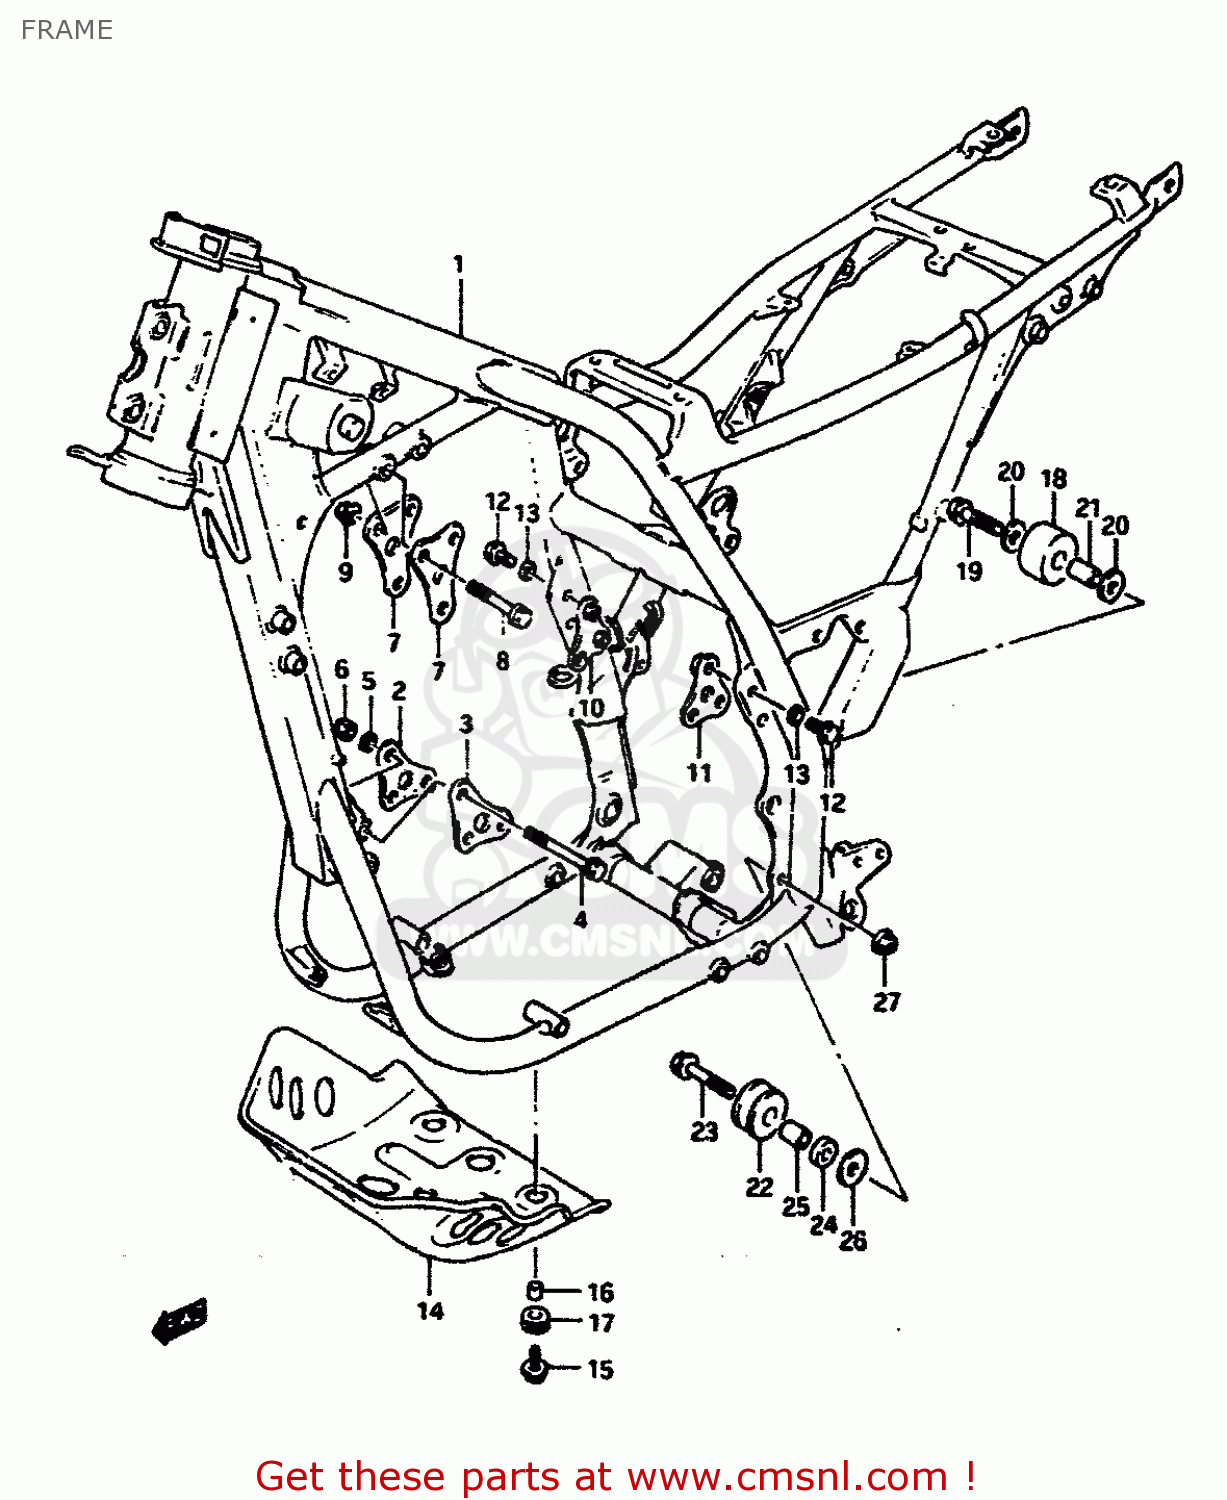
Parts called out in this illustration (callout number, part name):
1	FRAME (BLUE)
2	PLATE,ENG MTG FR,R
3	PLATE,ENG MTG FR,L
4	BOLT(8X72)
5	LOCK WASHER
6	NUT
7	PLATE,ENGINE MOUNTING
8	BOLT(8X50)
9	NUT
10	PLATE,ENG MTG RR,R
11	PLATE,REAR LH (WHITE)
12	BOLT(8X20)
13	LOCK WASHER
14	PROTECTOR,ENGINE
15	BOLT 6X20
16	SPACER (7X9X7)
17	CUSHION
18	ROLLER,CHAIN CONTROL
19	BOLT(8X41)
20	WASHER (8.2X24X1.6)
21	SPACER (8.6X13.8X28)
22	ROLLER,CHAIN CONTROL
23	BOLT 8X50
24	SPACER,LOWER
25	SPACER(8.6X12X25.5)
26	WASHER
27	NUT
